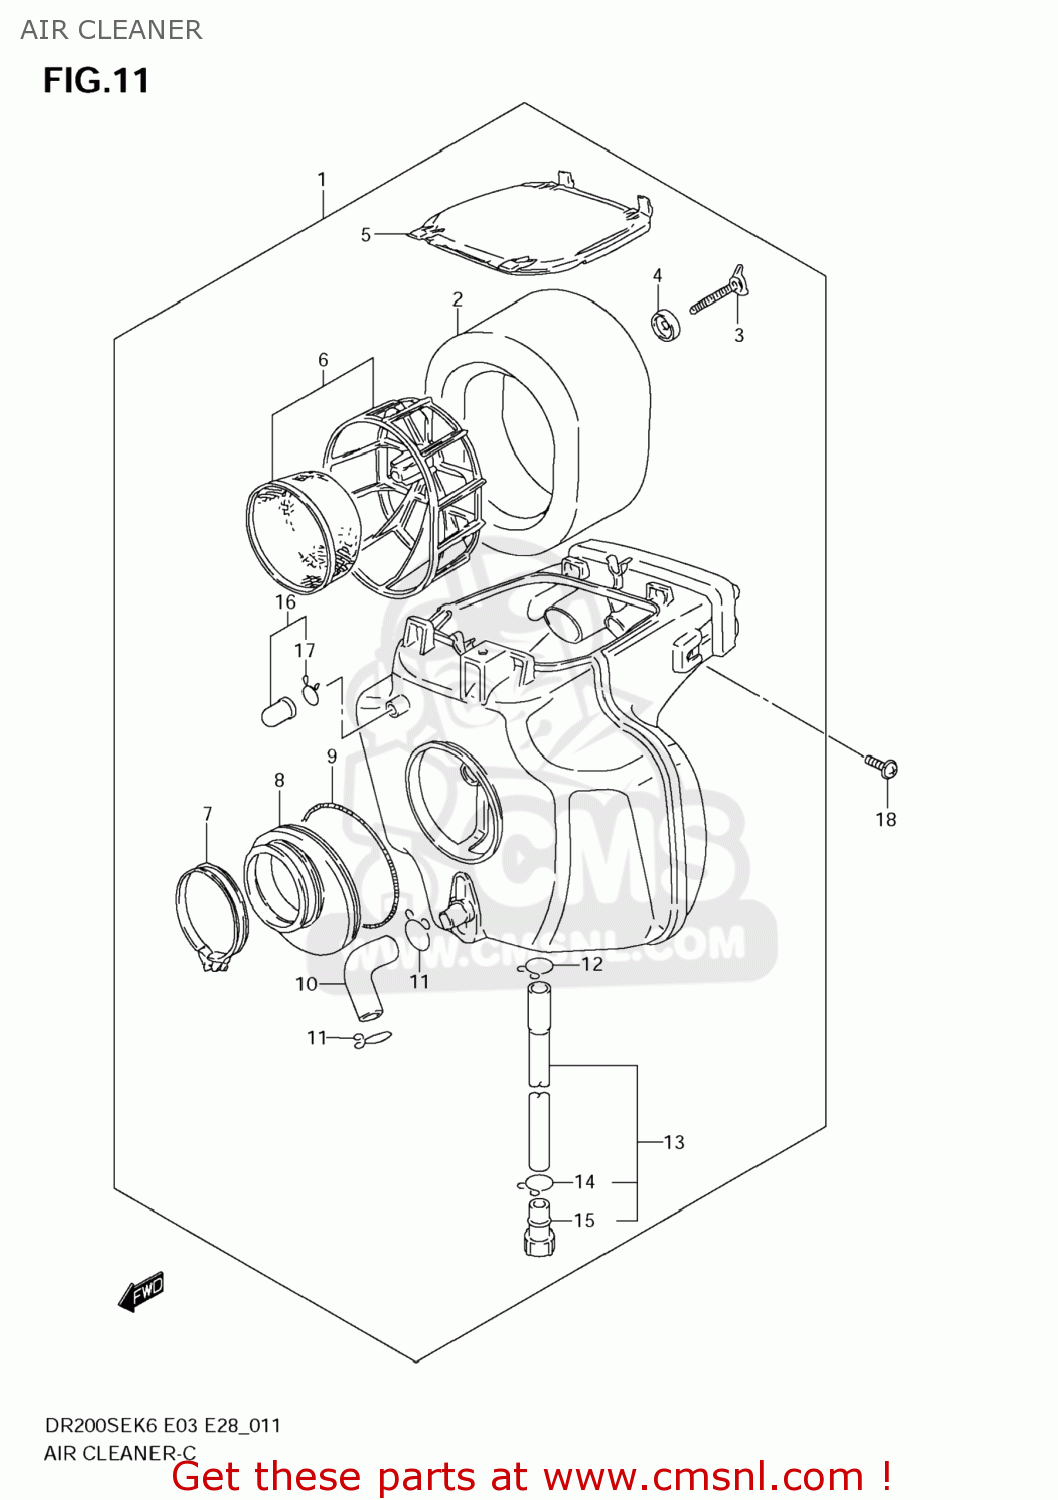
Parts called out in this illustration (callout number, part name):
1	CLEANER ASSY,AIR
2	FILTER
3	BOLT,WING
4	WASHER,FILTER HOLDER
5	CAP
6	HOLDER
7	CLAMP
8	TUBE,AIR CLEANER OUTLET
9	CLAMP,AIR CLEANER SIDE
10	TUBE,BREATHER
11	CLIP
12	CLIP
13	TUBE,DRAIN
14	CLIP
15	STOPPER,DRAIN
16	PLUG,DRAIN
17	CLIP
18	SCREW
